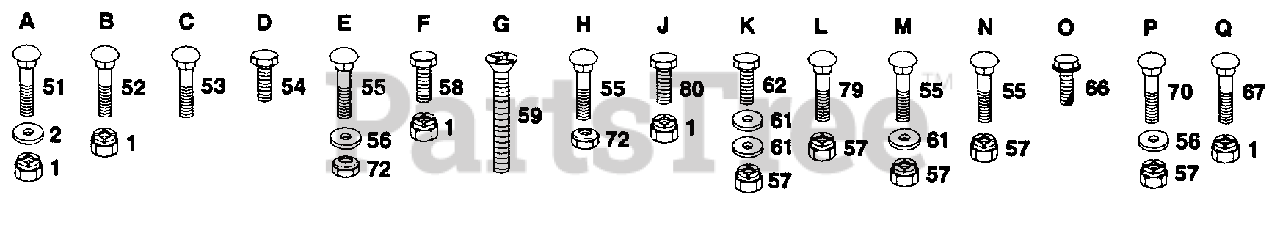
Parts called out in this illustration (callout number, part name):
2	WASHER
51	BOLT
53	BOLT
55	BOLT
56	WASHER
58	BOLT - HEX 3/8 - 16 X 3
59	SCREW YT
61	WASHER M
62	BOLT
66	SCREW
67	BOLT
79	BOLT
80	BOLT
